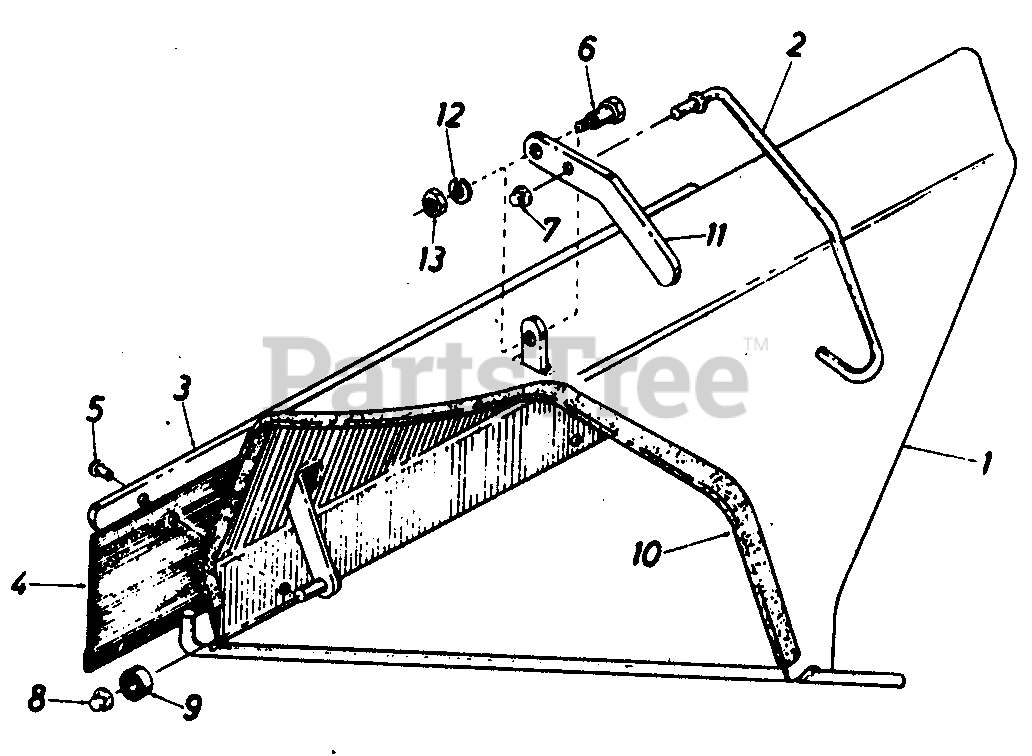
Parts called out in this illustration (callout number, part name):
1	Deflector Ass'y.
2	Hook Ass'y.
3	Retaining Strip
5	Rivet
6	Shld. Bolt .375" Dia. x .171 Lg.
7	Palnut 1/4" Rod
8	Palnut 3/8" Rod
12	L-Wash. 1/4" I.D.*
13	Hex Nut 1/4-20 Thd.*
